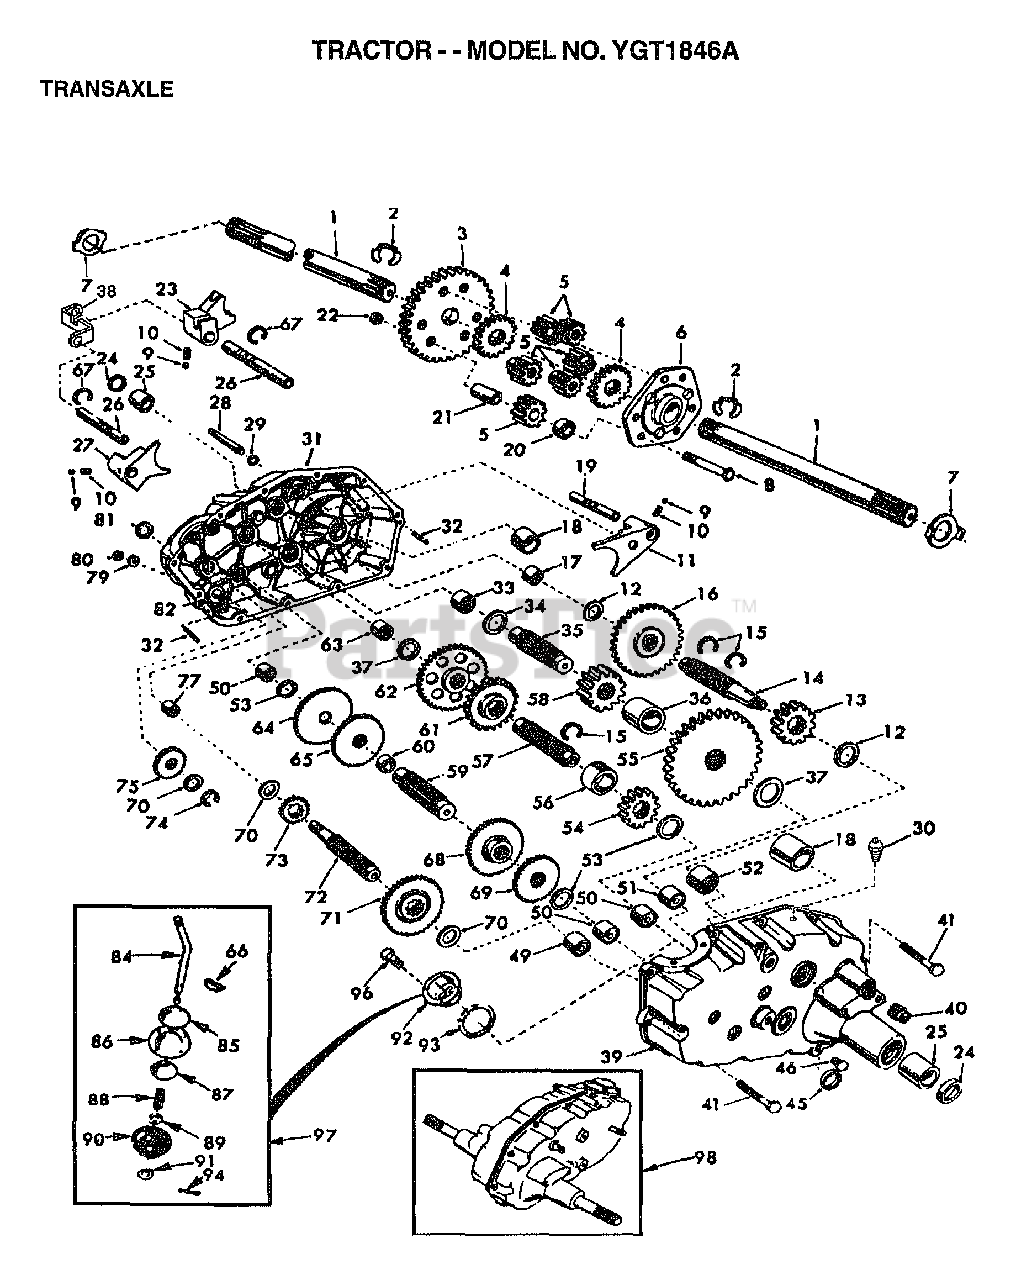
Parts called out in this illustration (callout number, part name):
1	SHAFT.AXLE.T
2	KLIP RING
3	FINAL GEAR T
4	DIFF GEAR T
5	DIFF PINION T
6	DIFF CARRIER T
8	BOLT
11	SHIFT FORK T
12	WASHER .T
13	RED PINION T
14	SHAFT BRAKE GT
15	SNAP RING T
16	GEAR T
17	"T, BEARING"
18	BEARING
19	SHAFT
20	SPACER T
21	PINION RS
22	GRIPCO NUT
23	FORK T
24	OIL SEAL STD
25	BRNG. T
26	SHIFT FORK SHAFT
27	SHIFT FORK T
28	SHIFT SHAFT
29	SEAL T
30	VALVE M
31	GEARCASE RH W/BER
32	PIN T
33	NEEDLE BRNG T
34	RACE T
35	GEAR SHAFT T
37	RACE T
38	GAT.LOWE.SHIFT.VGT
39	GEARCASE LH W/BER
40	PLUG PIPE
41	BOLT.5/16-18X1.25
45	SEAL T
49	"TI, BEARING"
50	NEEDLE BRNG T
51	NEEDLE BRNG T
52	"STD, BEARING"
53	BRNG RACE
54	RED PINION T
55	RED GEAR T
56	PINION SPACER T
57	GEAR SHAFT T
58	FINAL PINION T
59	GEAR SHAFT T
60	SPACER T
61	RED PINION T
62	RED GEAR T
63	RACE T
64	LOW SPEED GEA T
65	REVERSE GEAR T
66	KEY T
67	KLIP RING
68	INTERMED GEAR T
70	"T, BEARING"
71	CLUSTER GEAR T
72	SHAFT INPUT
73	LO SPEED PINION T
74	KLIP RING
75	IDLER GEAR T
77	NEEDLE BEARING TI
79	WASHER T
80	NUT
81	SEAL STD
82	SHAFT REVERSE IDL
84	GEAR SHIFT LVR T
85	CAP T
86	COVER AND PIN T
87	GUIDE BALL T
88	SPRING TI
89	WASHER
90	SEAL T
91	WASHER
92	GEAR SHIFT GA T
93	GASKET T
94	COTTER PIN
96	SCREW.HX.W.HD.MAC
97	GEAR SHFT LVR T
98	TRANSAXLE ASM 6SP
